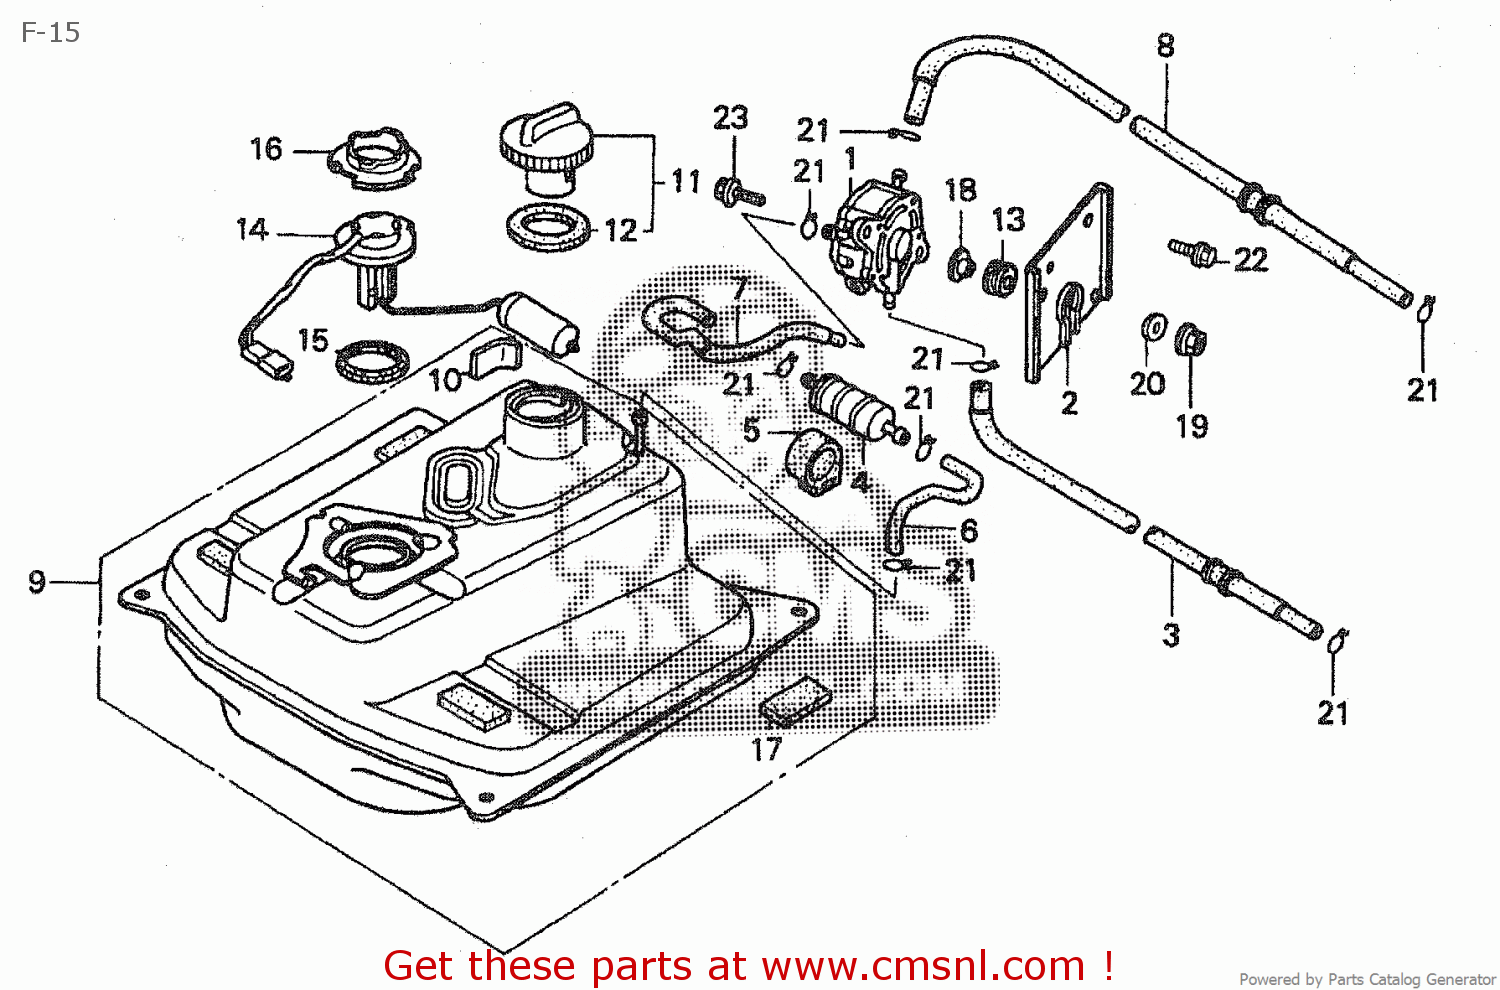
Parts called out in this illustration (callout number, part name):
1	PUMP ASSY,FUEL
2	STAY FUEL PUMP
3	TUBE,PULSE
4	STRANER COMP.,
5	CUSH FUEL STRANER
6	TUBE A,FUEL STRAI
7	TUBE B,FUEL STRAI
8	TUBE,FUEL PUMP
9	TANK COMP.,FUEL
11	CAP COMP.,FUEL FI
12	PACKING,FUEL FILL
13	GROMMET,WIRE HARN
14	FUEL UNIT
15	PACKING,BASE
16	RET,FUEL UNIT
17	RUBBER,TOOL BOX
18	COLLAR,DISTANCE
19	NUT,FLANGE,6MM
20	WASHER,PLAIN,6MM
22	BOLT,FLANGE,6X12
23	BOLT,FLANGE,6X25
